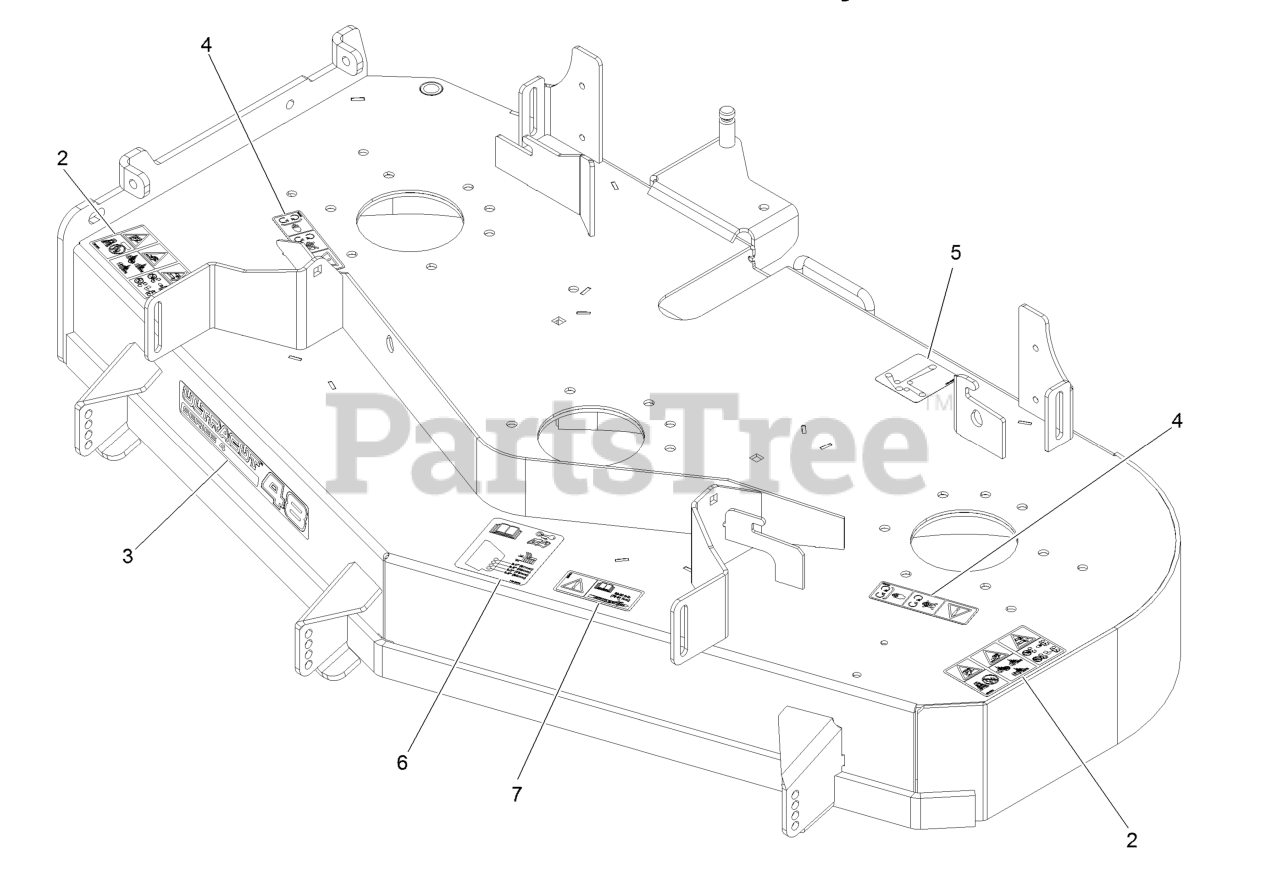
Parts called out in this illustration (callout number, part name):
2	Decal-Danger Thrown Objects
3	Decal, 484
4	Decal-Missing, Cover
5	Decal-Belt Routing
6	Decal-Roller, Anti-Scalp
7	Decal-Bolt Torque
